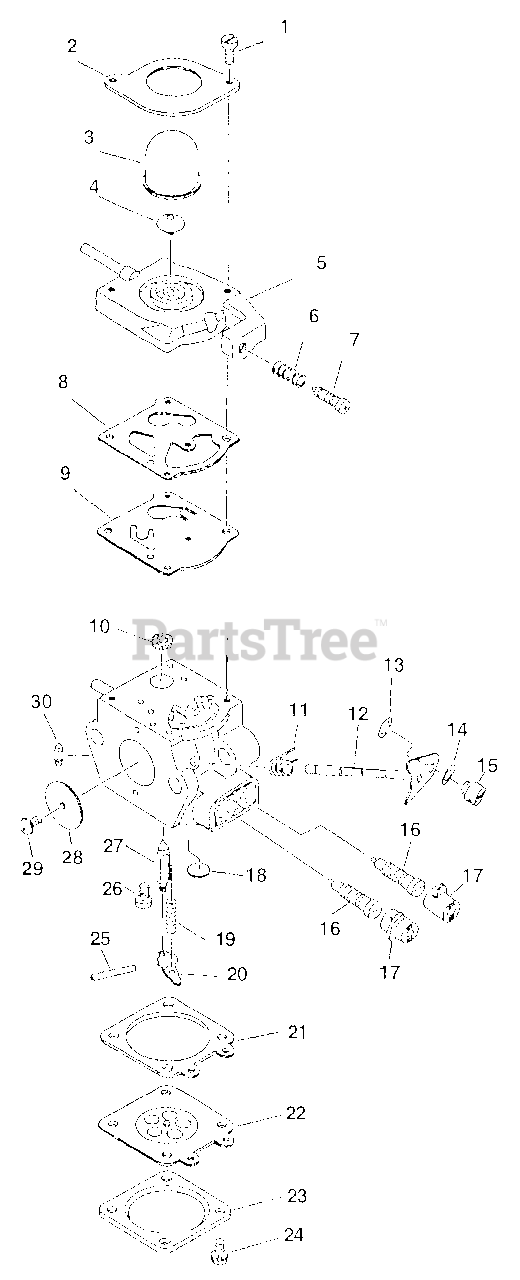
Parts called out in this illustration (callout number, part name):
2	RETAINER, PURGE BULB
3	BULB, PURGE
4	VALVE, CHECK
5	COVER, FUEL PUMP
6	SPRING, IDLE ADJUST
7	SCREW, IDLE ADJUST
10	STRAINER
11	SPRING, THROTTLE RETURN
12	SHAFT, THROTTLE
16	NEEDLE - MIXTURE
17	CAP, LIMITER
18	PLUG, WELCH
19	SPRING, METERING LEVER
20	LEVER, METERING
21	GASKET, METERING
22	DIAPHRAGM, METERING
23	COVER, METERING DIAPHRAGM
24	SCREW
25	PIN, METERING LEVER
26	SCREW, METERING LEVER PIN
27	VALVE, INLET NEEDLE
28	VALVE, THROTTLE
31	DIAPHRAGM/GASKET KIT
32	REPAIR KIT, CARBURETOR
